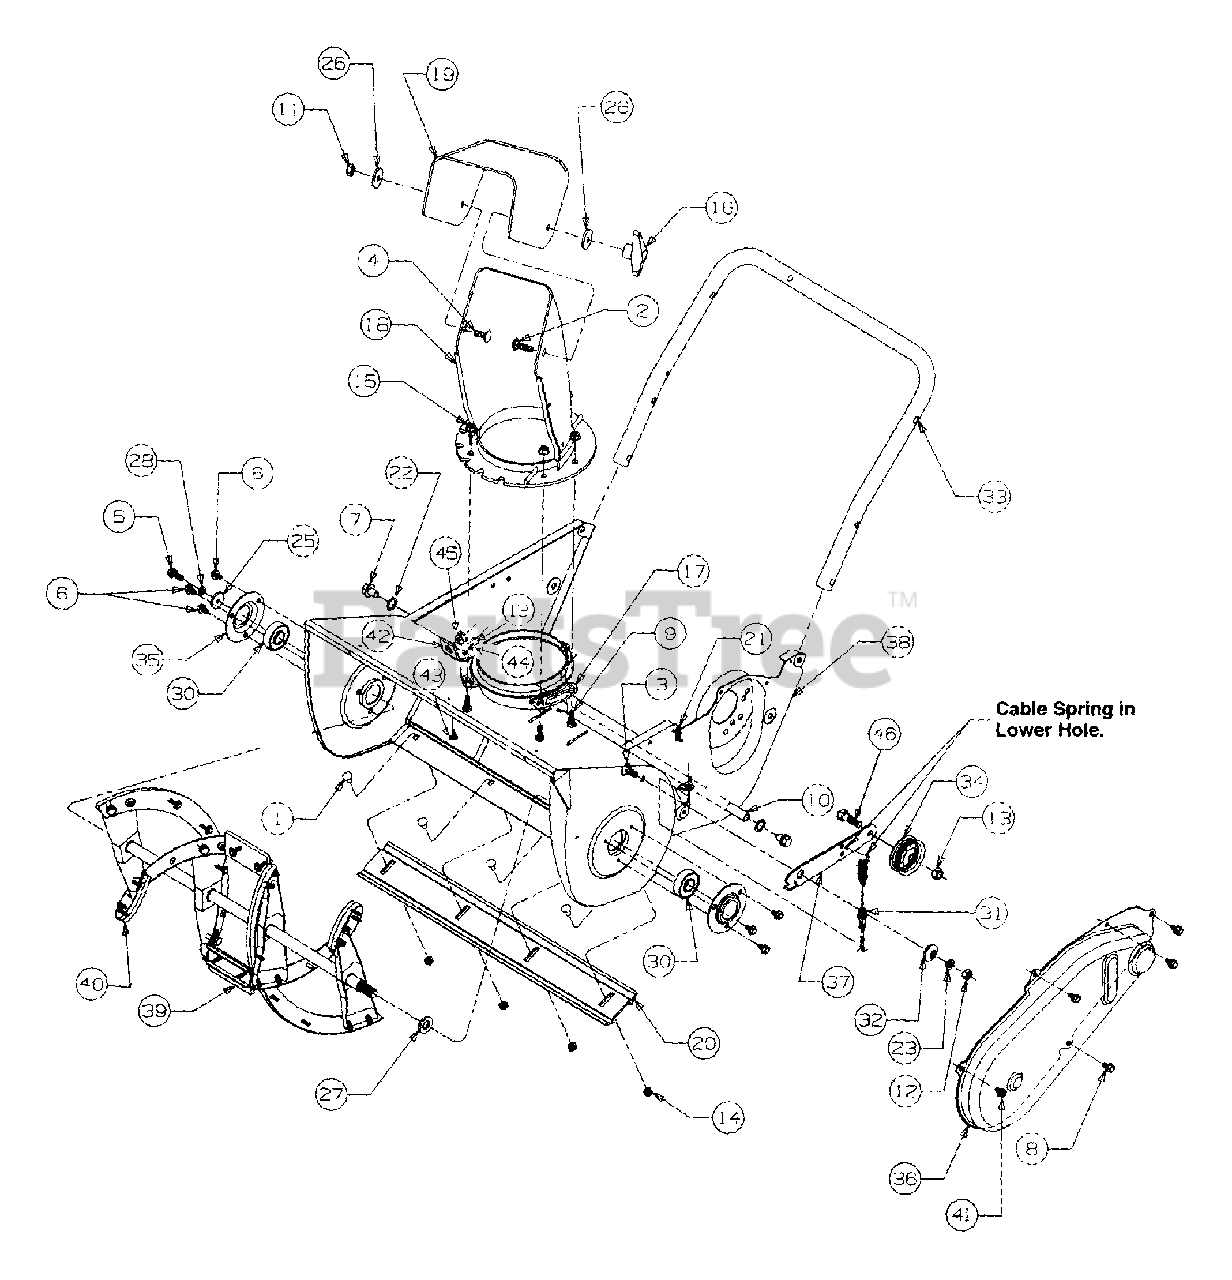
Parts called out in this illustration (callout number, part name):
1	Bolt - Carriage
2	Bolt - Carriage
3	Screw - Pan Head
4	Bolt - Carriage
5	Screw - Hex Washer
6	Screw - Hex Washer
7	Screw - Hex Washer
8	Screw - Hex Washer
9	Screw - Hex Cap
10	Axle
11	Nut - Hex Center Lock
12	Nut - Hex
13	Nut - Hex Lock
14	Hex Lock Flange Nut
15	Nut - Hex Lock Flanged
17	Keeper - Chute
18	Chute - lower
19	Chute - Upper
20	Shave Plate
21	Spring - Extension
22	Washer - Flat
23	Washer - Lock
25	Washer - Flat
26	Washer
27	Washer - Flat
28	Washer - Lock
30	Ball Bearing
31	Cable - Clutch
32	Spacer - Shoulder
40	Auger Rubber
41	Screw - Hex Washer
44	Washer - Bell
45	Bushing
46	Screw - Cap
